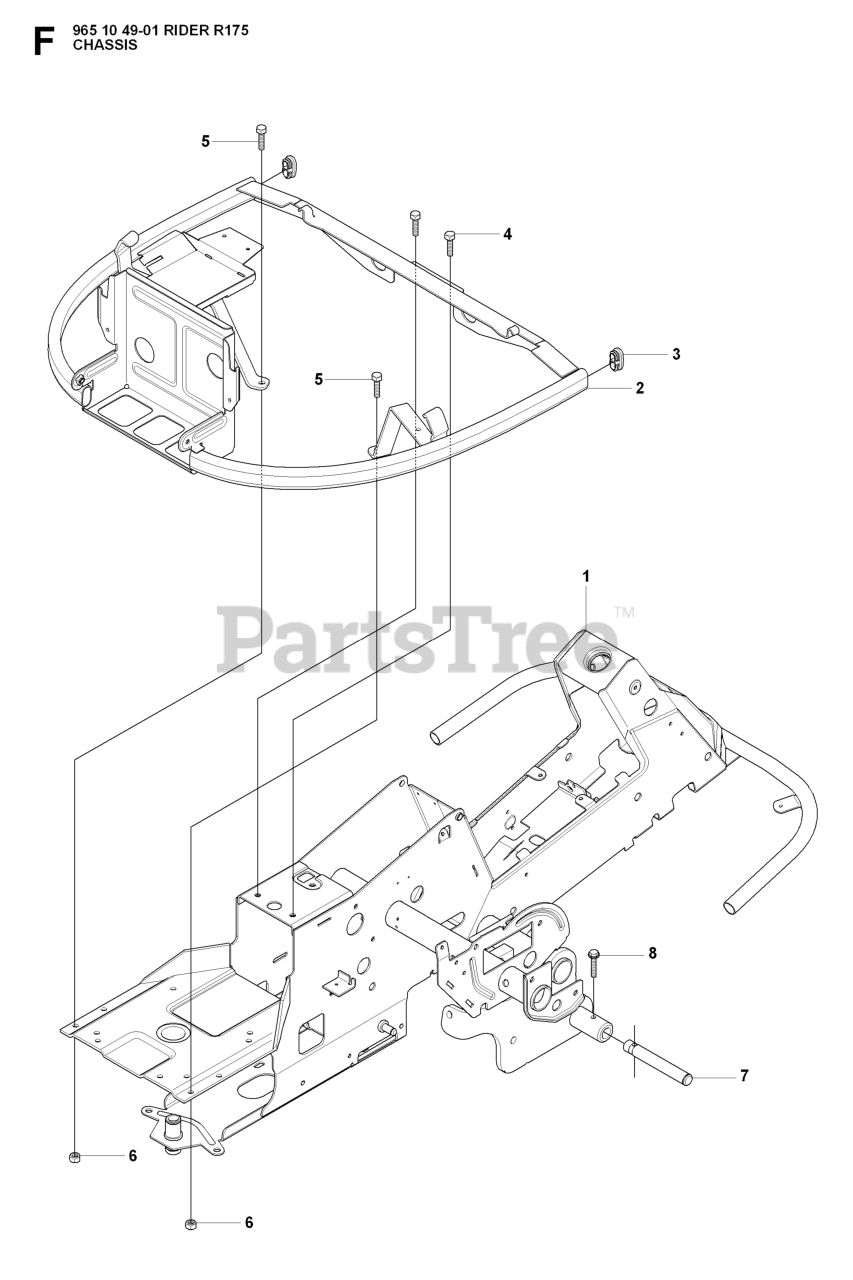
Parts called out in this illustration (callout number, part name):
2	ENGINE FRAME
6	LOCKNUT M8
8	BOLT FLANGE - M8X40\
